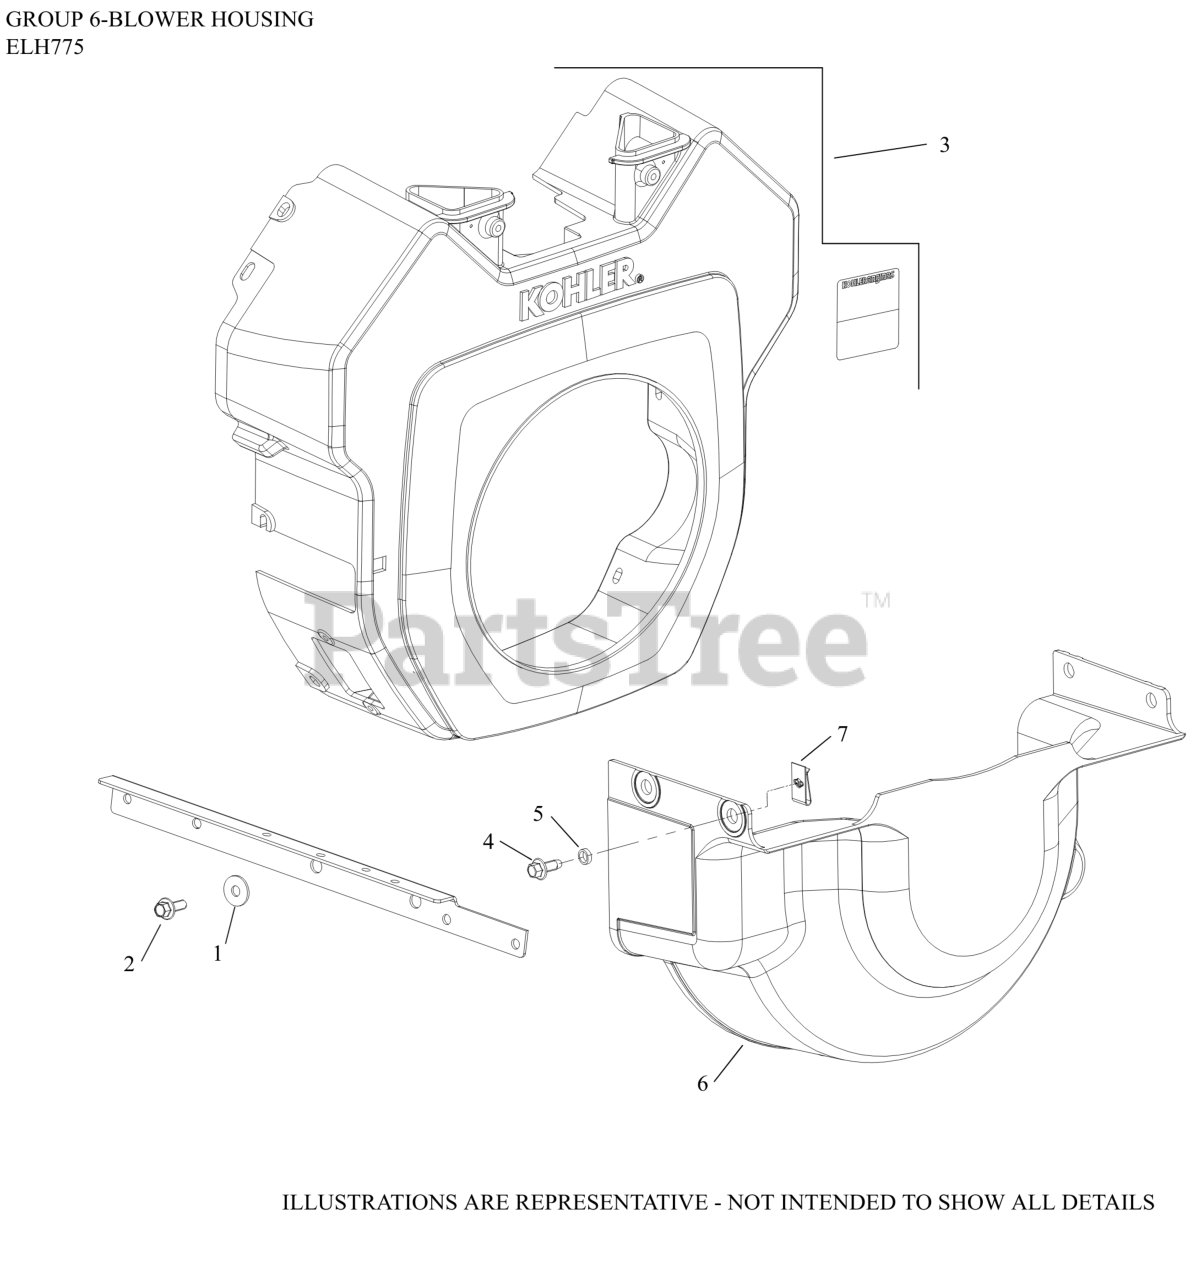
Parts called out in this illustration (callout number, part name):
1	WASHER, FLAT 1/4"
4	SCREW, THREAD FORMING
6	COVER, ENGINE FLYWHEEL
